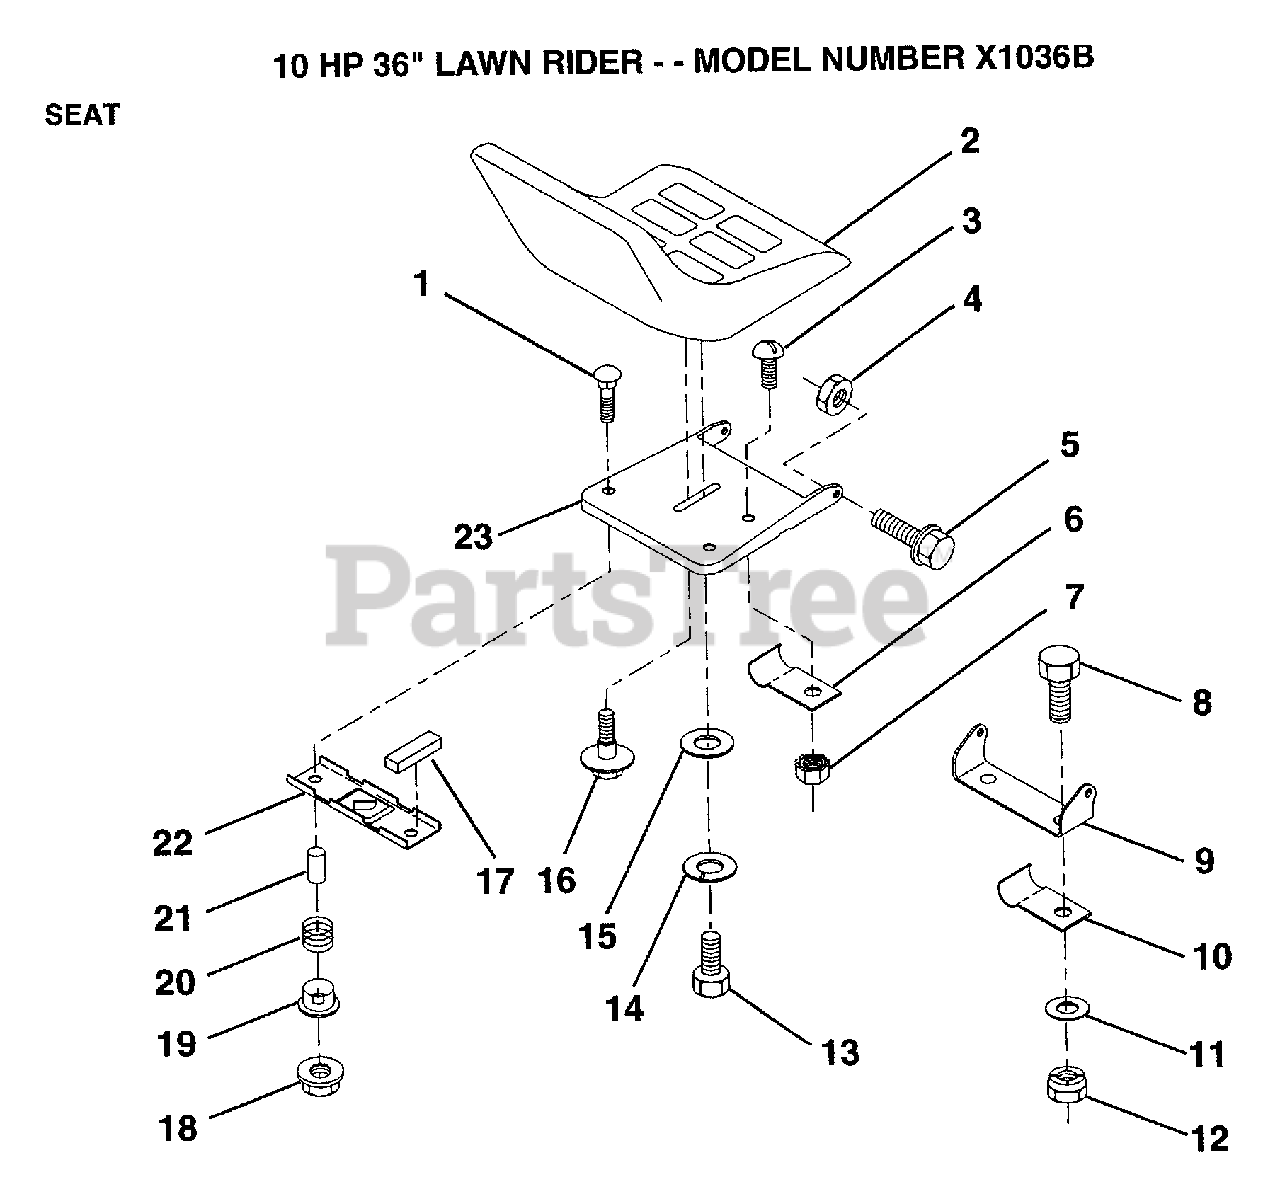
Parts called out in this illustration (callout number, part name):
7	"NUT,KEPS"
10	"CLIP,INSULATOR"
11	WASHER
13	BOLT
14	LOCKWASHER
15	WASHER
16	"BOLT,SHOULDER"
17	STRIP FORM
19	BUSHING
20	SPRING
21	SPACER SPLIT
22	BRKT SWITCH
